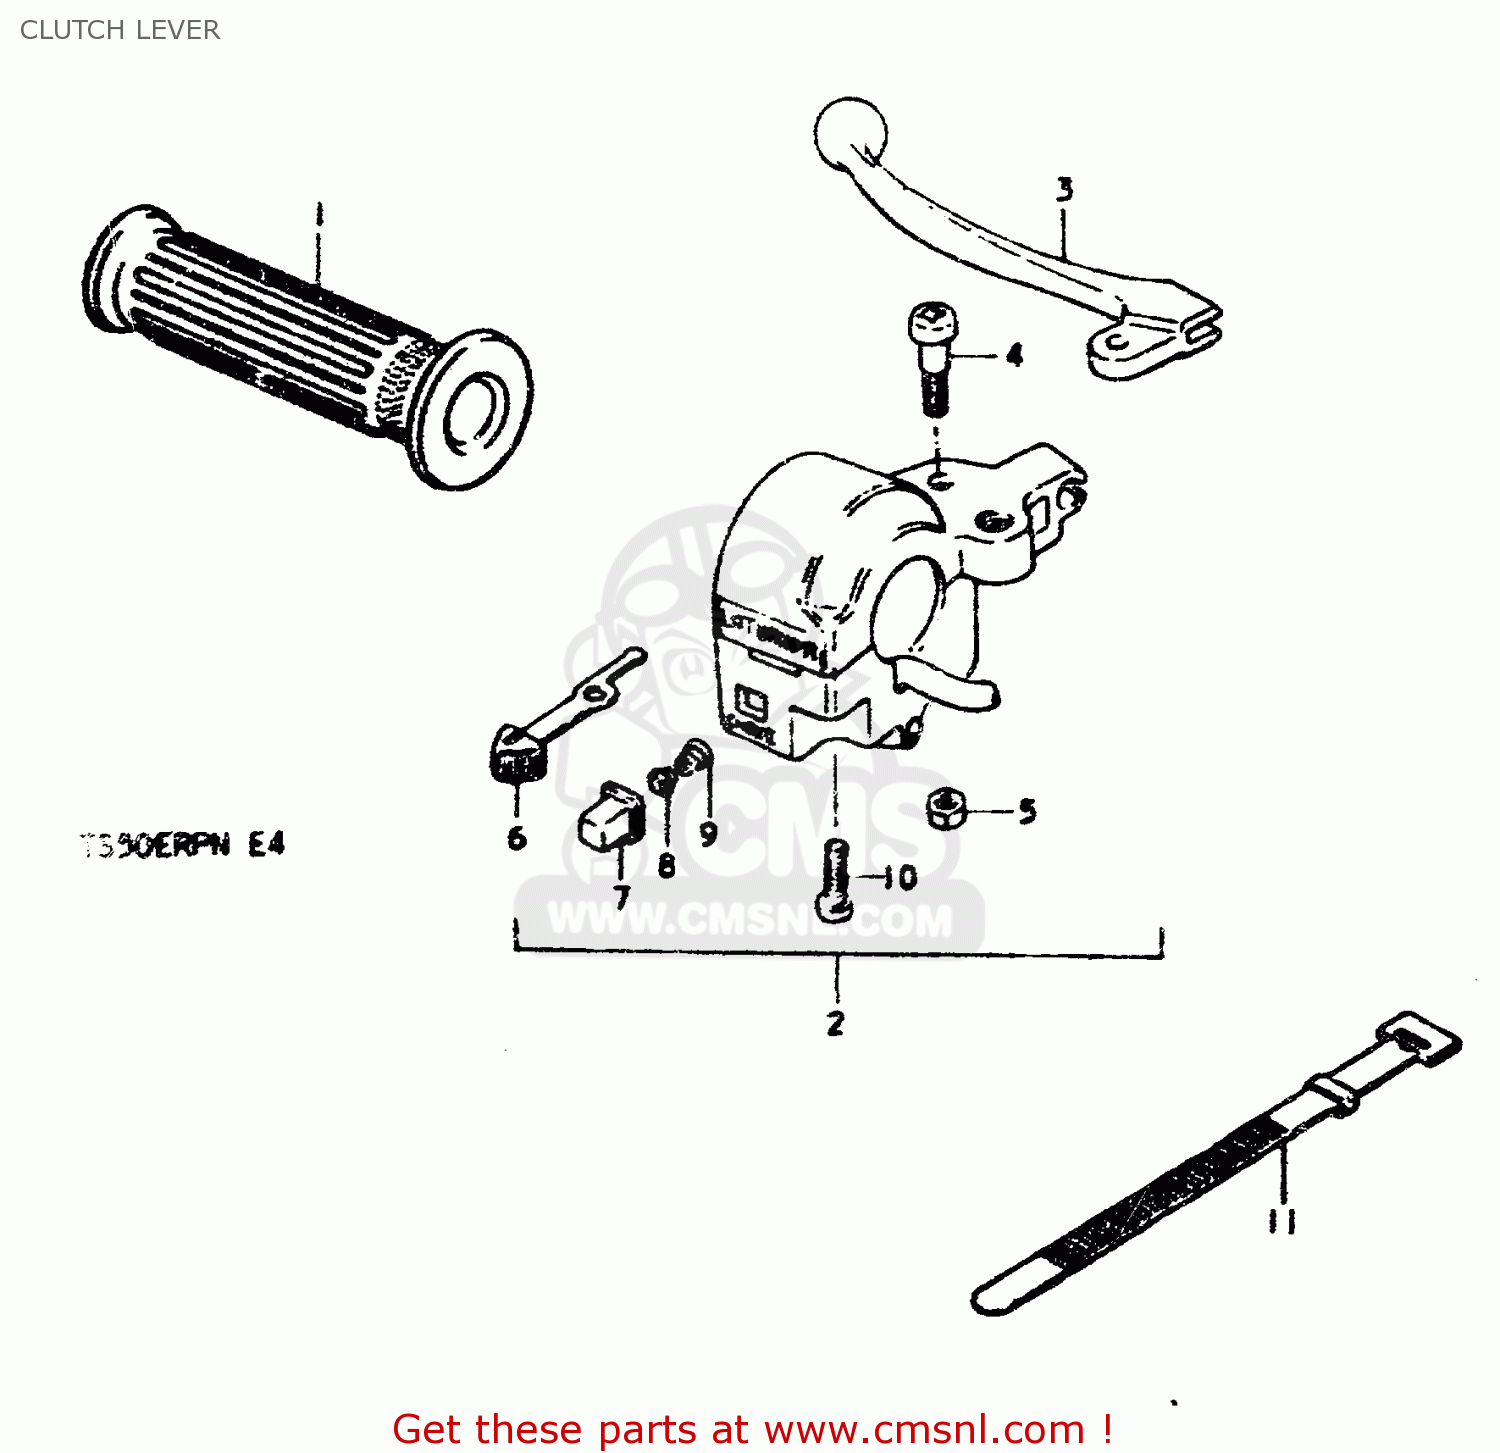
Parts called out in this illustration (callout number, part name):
1	GRIP,L
2	CLUTCH LEVER ASSY
3	LEVER
4	BOLT,LEVER
5	NUT,LEVER BOLT
6	KNOB,TURN SIGNAL SWITCH
7	BUTTON,HORN
8	CONTACT
9	SPRING
10	SCREW
11	CLAMP(L:120)
